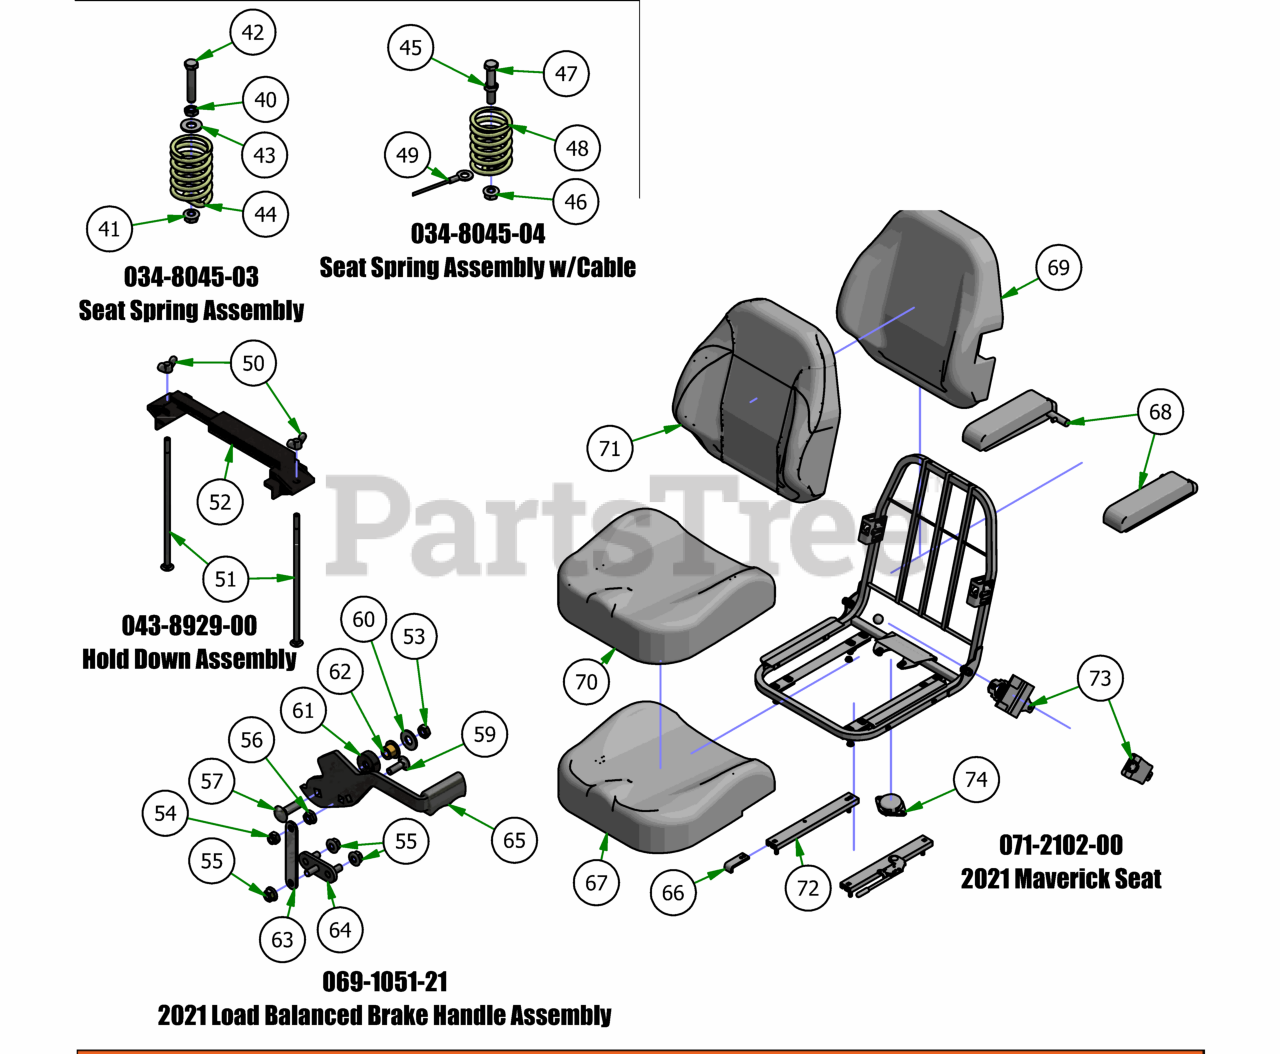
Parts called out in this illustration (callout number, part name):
40	3/8-16 Half Jam Nut
41	3/8-16 HEX SERRATED FLANGE NUT HARD/ZINC
42	3/8-16 X 2 HEX CAP SCREW (GR.5) ZINC
43	3/8 FLAT WASHER USS (1" OD) ZINC
44	Seat Spring
45	3/8-16 Half Jam Nut
46	3/8" Flange Nut
47	3/8"-16 x 2" Gr 5 Hex Bolt
48	Seat Spring
49	Seat Cable
50	1/4" Wing Nut
51	1/4-20 X 8 Carriage Bolt
52	Battery Hold Down
53	3/8-16 HEX JAM 2-WAY REVERSIBLE CENTER LOCKNUT
54	5/16-18 NYLON INSERT CAP LOCKNUT ZINC (BLK CAP)
55	5/16-18 NYLON INSERT FLANGE LOCKNUT ZINC
56	5/16-18 HEX SERRATED FLANGE NUT HARD/ZINC
57	3/8-16 X 1-1/4 CARRIAGE BOLT ZINC
59	5/16-18 X 1 CARRIAGE BOLT (GR.8) ZINC
60	3/8 FLAT WASHER USS (1" OD) ZINC
61	2015 Brake Lever Spacer
62	.377 ID X .625 OD X .500 HGT X .880 FLNG DIA X .060 FLNG
63	Brake Cable Extension Plate
64	Brake Load Balancer Lower Weldment
65	Load Balanced Brake Handle with Grip
66	Black Seat stop from Seat King
67	Seat Cover Molded Foam for 071-2040-18/071-5080-18
68	2017 ZT/Maverick/2020 ZTElite/Avenger Arm Rest Kit
69	Foam Molded Back for 071-2102-00
70	Seat Cover for 071-2101-00/071-2102-00
71	Back Cover for 071-2102-00
72	Seat Rails for Outlaw Seat/2020 ZT Elite/ZTAvenger
73	Seat Belt for 071-5080-17
74	13/14 MZ/Outlaw Seat Switch
